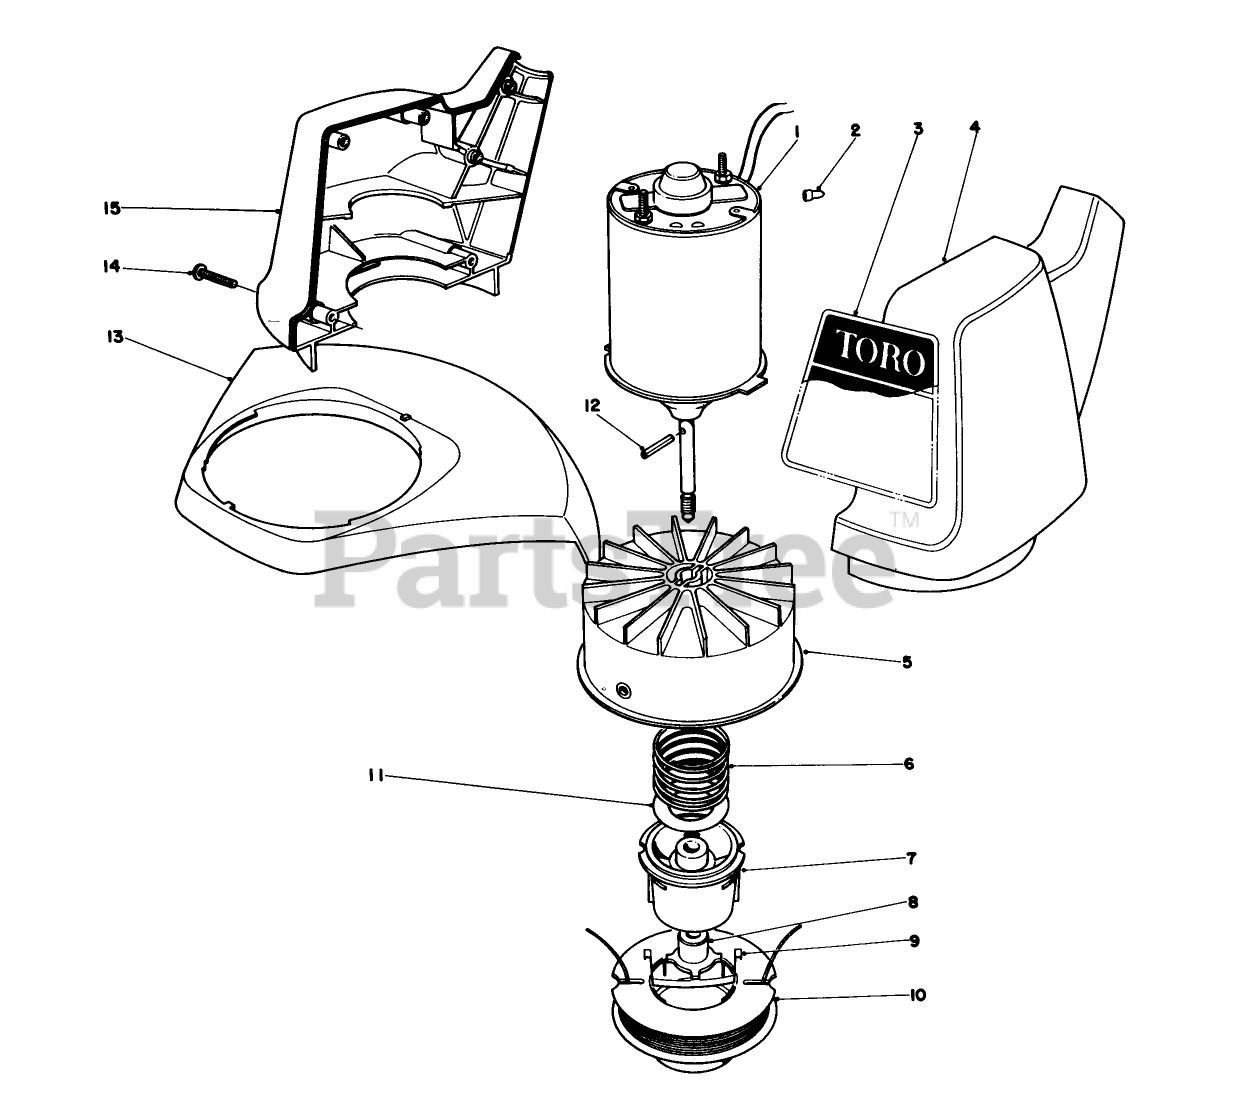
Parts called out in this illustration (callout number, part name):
1	MOTOR
2	CONNECTOR WIRE JOINT
3	Decal 1200
4	Housing-L.H.
5	DRUM W/EYELET
6	SPRING COMPRESSION
7	SPOOL CORE
8	DRIVER
9	SADDLE-SPOOL CAP
10	Prewound Spool (Incl. Ref. #9)
11	Spool Only
12	COIL PIN
13	SHIELD ASM
14	SCREW-PPH
15	Housing-R.H.
